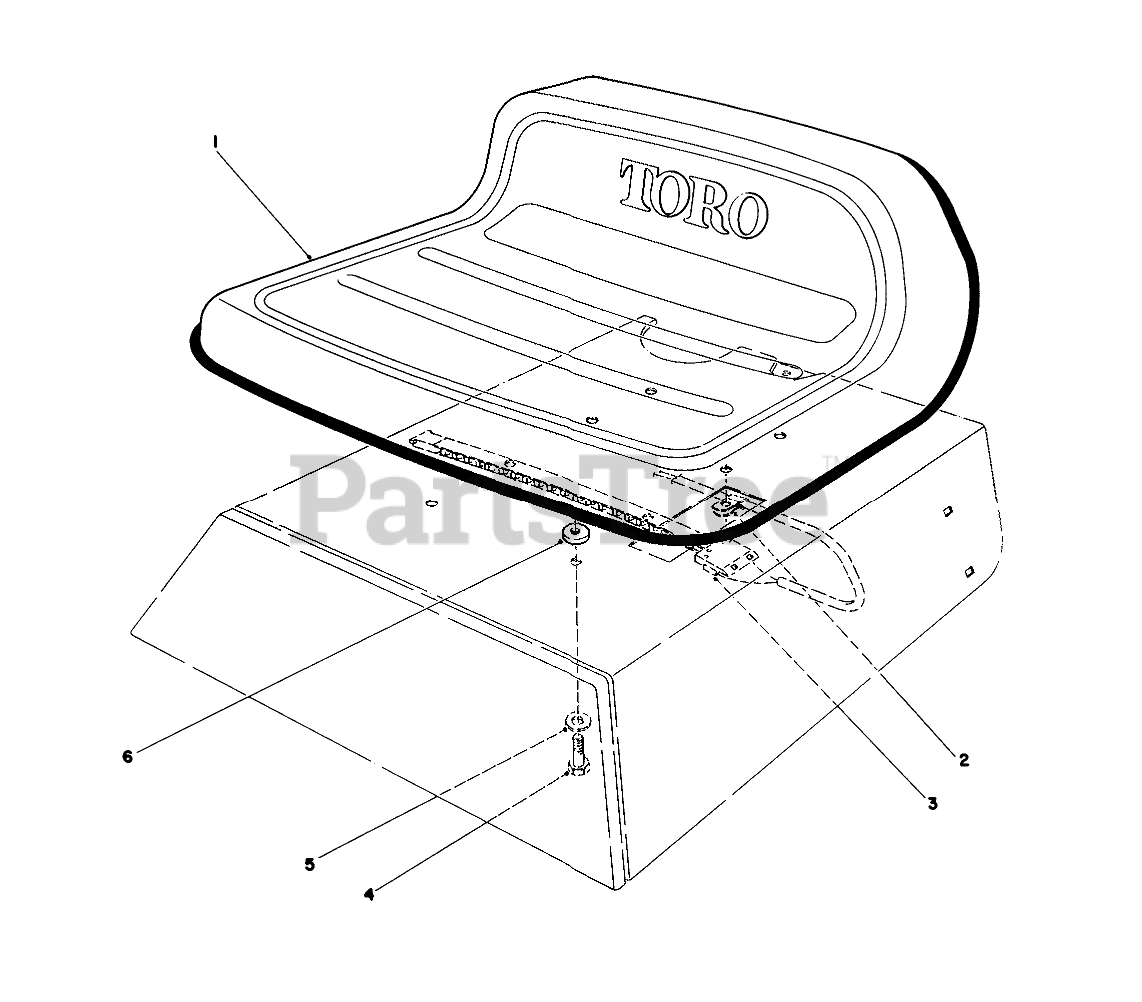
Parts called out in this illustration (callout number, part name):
1	Seat
2	CLIP-FUEL LINE
3	SWITCH-SEAT
4	SCREW-HH
5	WASHER-FLAT
6	SPACER-PIN, MOUNTING
